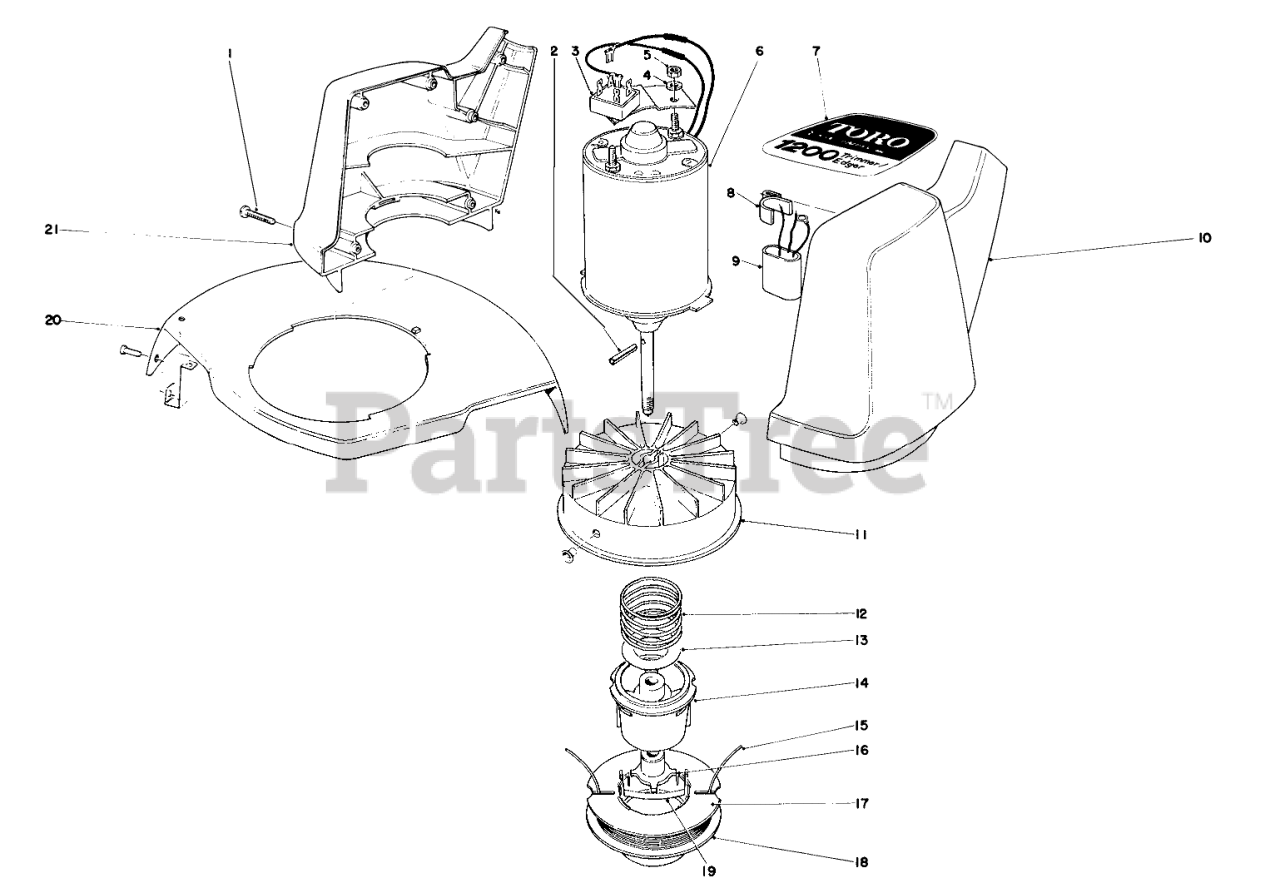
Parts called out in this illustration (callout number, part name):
1	SCREW-PPH
2	COIL PIN
3	Bridge Rectifier Assembly
4	WASHER-LOCK, EXT
5	NUT-HEX
6	Motor
7	Toro 1200 Decal
8	Clamp-Suppressor
9	Suppressor
10	LH MOTOR HSG (RED)
11	Drum W/Eyelets
12	SPRING COMPRESSION
13	WASHER-FLAT
14	SPOOL CORE
15	50-Coil.065" Cutting Line
16	Driver
17	Empty SPooI
18	Prewound Spool
19	SADDLE-SPOOL CAP
20	Shield with Cut Off Blade
21	Right Motor Housing
